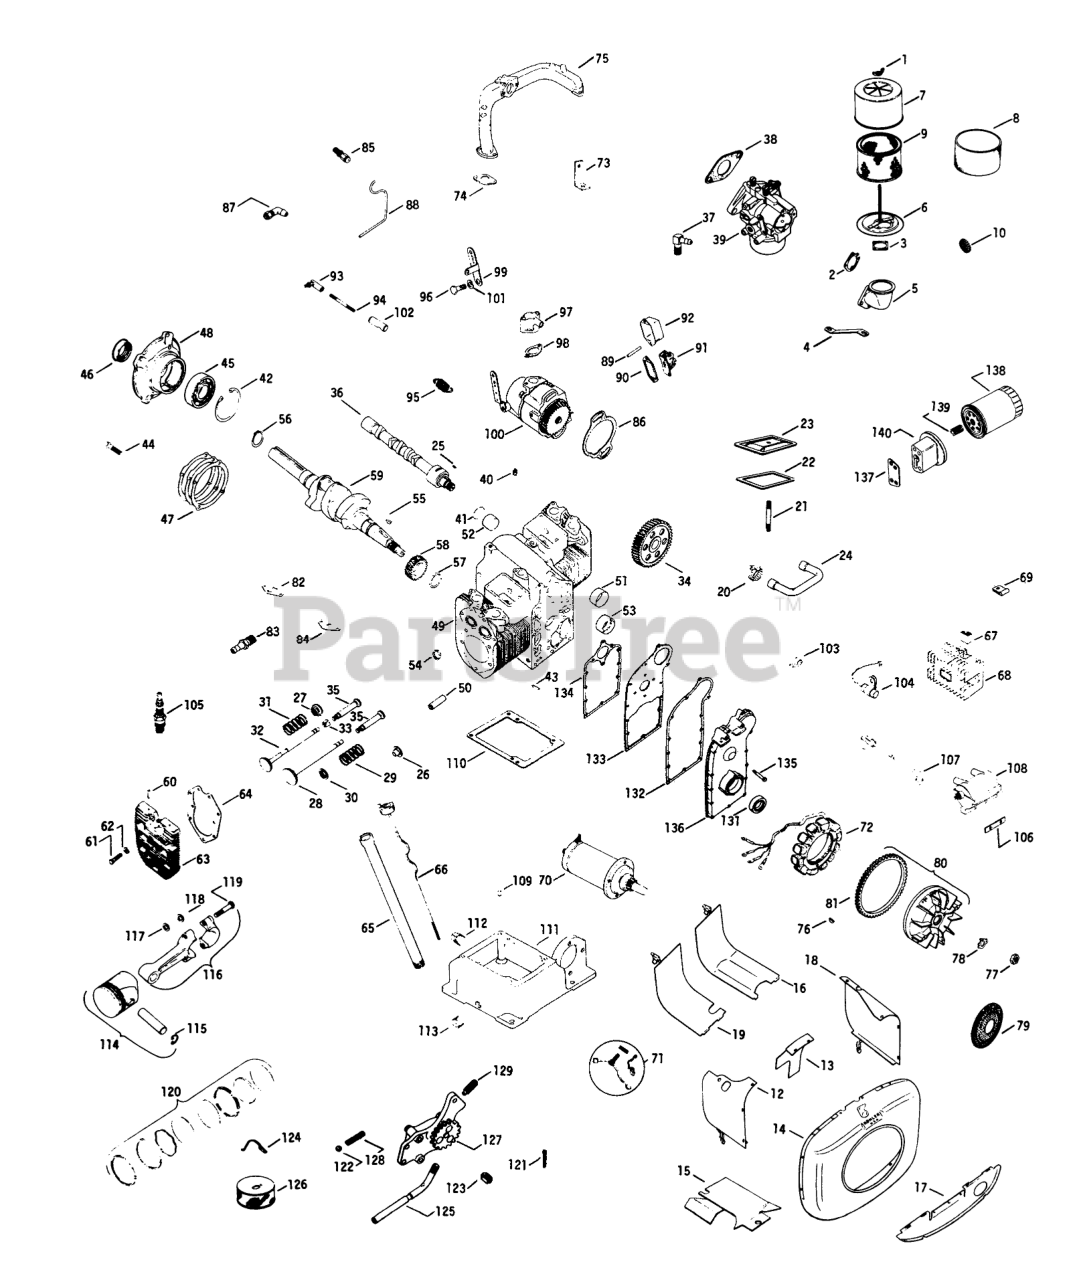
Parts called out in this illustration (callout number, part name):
1	Nut-Wing
2	Gasket
3	Gasket-Air Cleaner
4	Brace elbow
5	Elbow air cleaner
6	Base-Air Cleaner
7	Cover-Air Cleaner
8	Element
9	Element
10	Screen
10	Screen, elbow
12	Baffle #1 Cyl. Hd.
13	Baffle, #1 Upper Cyl.
14	Housing, Blower
15	Baffle
16	Baffle #2 Barrel
17	Baffle-Housing Support
18	Baffle #2 cylinder head
19	Baffle, #1 barrel
20	Clamp-Hose
21	Stud, valve cover
22	Gasket-Valve Cover
23	Cover-Valve
24	Hose-Breather
25	Key-Woodruff
26	Retainer-Spring
27	Rotator
28	Valve-Intake
29	Spring
30	Retainer-Spring
31	Spring
32	Valve exhaust
33	Keeper, Valve
34	Gear, Camshaft
35	Tappet
36	Camshaft
37	Elbow
38	Gasket
39	Carburetor-assembly (Replaced by 48 053 12)
40	Plug
40	Plug, Pipe
41	Plug-Welch
42	Pin
43	Pin
44	Screw-H.C.
45	Bearing-Ball
46	Seal-Rear Oil
47	Gasket-Closure Plate
48	Plate, rear closure
49	Crankcase-assembly
50	Guide Valve
51	Bushing
52	Bushing
53	Bearing
54	Insert
55	Key
56	Ring-Retaining
57	Ring-Retaining
58	Gear, crankshaft
59	Crankshaft
60	Pin, Roll 3/16x1-1/8
61	Screw
62	Washer
63	Head, Cylinder
64	Gasket, Cylinder Head
65	Tube, dipstick
66	Dipstick
67	Connector
68	Regulator
69	Clip
70	Starter Assembly
71	Kit, Brush
72	Stator
73	Lift Cable
74	Gasket
75	Manifold, Intake
76	Key-Woodruff
77	Nut-Hex.
78	Nut-Lock
79	Screen, grass
80	Flywheel-assembly
81	Gear, Ring
82	Gasket, pump
83	Connector
84	Cover, fuel pump
85	Connector
86	Gasket-Governor Housing
87	Elbow
88	Line, Oil
89	Rod, Breaker Push
90	Gasket, Cover
91	Breaker
92	Cover
93	Ball Joint
94	Rod-Throttle
95	Spring Governor
96	Screw Shoulder
97	Housing, breather (Includes valve)
98	Gasket
99	Lever-Throttle
100	Governor
101	Washer
102	Ball Joint
103	Clip-Cable
104	Condenser
105	Plug, spark
106	Plate Coil Mounting
107	Lead high tension
108	Coil
109	Pin-Dowel
110	Gasket-Oil Pan
111	Pan, oil-assembly
112	Plug
113	Plug, Pine
114	Piston - assembly (Std.) (Includes pin & retainers)
115	Pin, Retainer
116	Rod, conn.-assembly (Std.)
117	Washer
118	Washer
119	Screw, connecting rod
120	Ring set (Std. & .003) (Svc)
121	Pin-Cotter
122	Ball Steel
123	Palnut
124	Clip-Oil Tube
125	Tube-Oil Inlet
126	Strainer-Oil
127	Pump
128	Spring, Relief Valve
129	Screw
131	Seal rear oil
132	Gasket-Gear Cover
133	Plate-Gear Cover
134	Gasket-Gear Cover Plate
135	Screw-H.C.
136	Cover, gear
137	Gasket, adapter
138	Filter-Oil
139	Nipple
140	Adapter, filter
